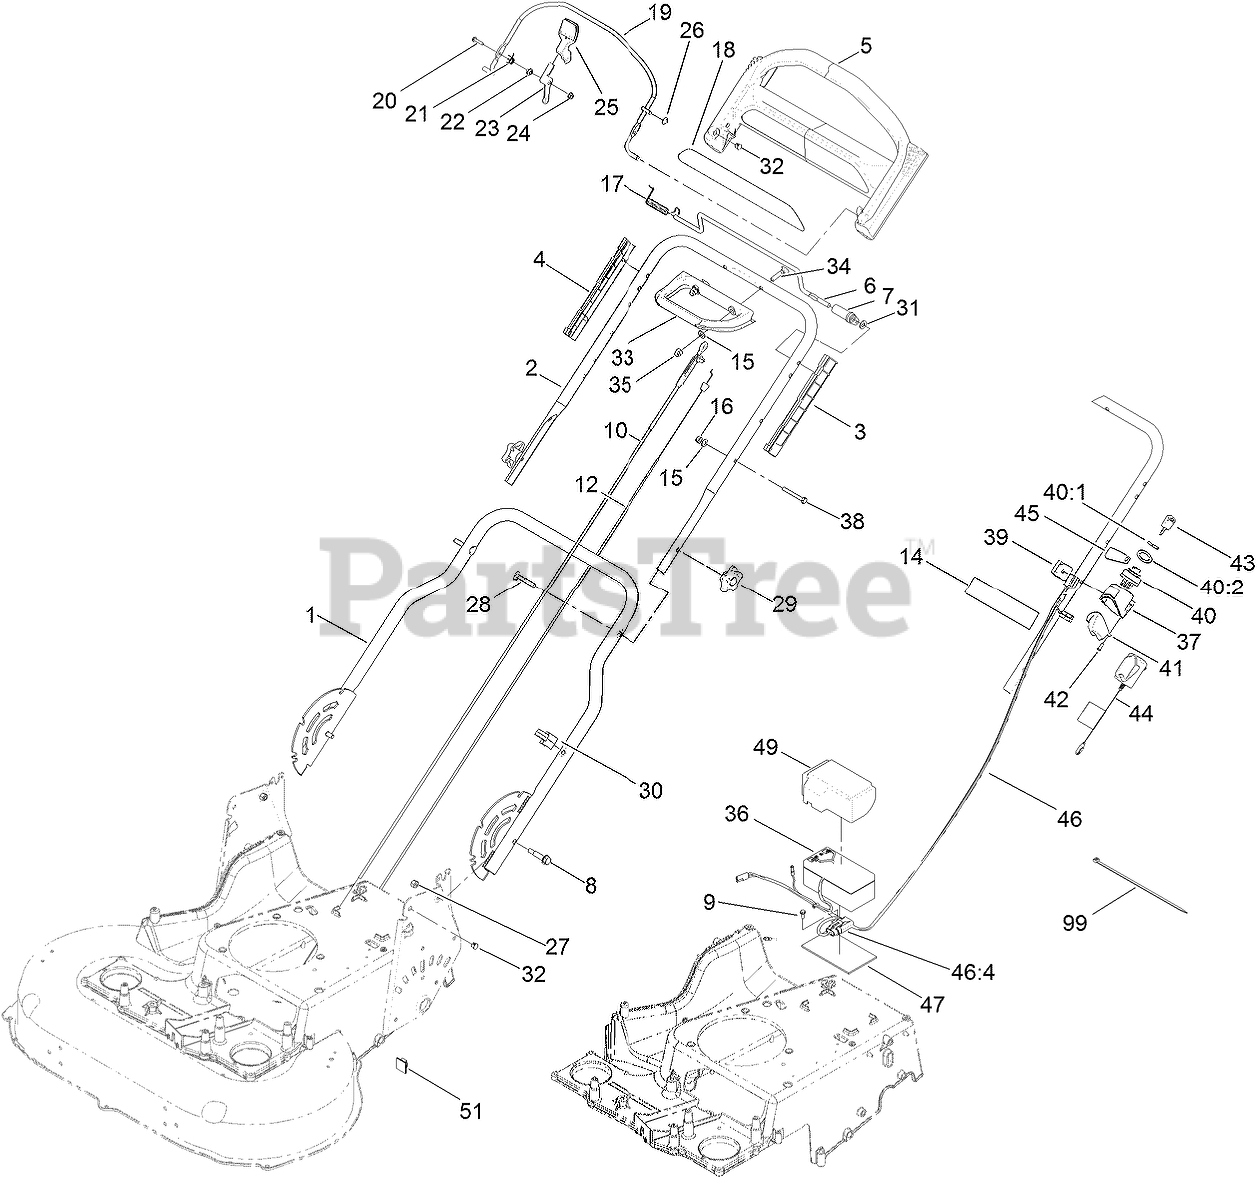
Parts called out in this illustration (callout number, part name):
1	HANDLE-LOWER
2	HANDLE-UPPER
3	GUIDE-LH
4	GUIDE-RH
5	HANDLE-CONTROL
6	BAR-CONTROL, TRACTION
7	LEVER-TRACTION
8	BOLT-SHOULDER, HHF
9	SCREW-TAPTITE
10	CABLE-BRAKE, BBC
12	CABLE-TRACTION
14	DECAL-WARNING
15	WASHER-FLAT
16	NUT-LOCK, NI
17	Spring-Torsion
18	DECAL-HANDLE
19	BAIL-BRAKE
20	SCREW-HWH
21	SPRING-TORSION
22	SPACER
23	LEVER
24	NUT-LOCK, FLANGE
26	NUT-SPEED
27	NUT-LOCK, NI
28	SCREW-HANDLE
29	KNOB-HANDLE
30	GUIDE-CABLE
31	WASHER-PLAIN
32	Plug-Dome
33	HANDLE-ASSIST, TRACTION
34	SCREW-HANDLE
35	NUT-HEX, NYLON CAP
36	BATTERY-WET
37	HOUSING-SWITCH, KEY
38	SCREW-HH
39	ANCHOR-CABLE, UPPER
40	SWITCH-STARTER
40:1	NUT-HH
40:2	WASHER-TOOTH, INTERNAL
41	COVER-SWTCH
42	SCREW-PPH
44	CHARGER-CE
45	DECAL-SWITCH, IGNITION
46	HARNESS-WIRE
46:4	FUSE-40 AMP
47	FOAM-BATTERY
49	COVER-BATTERY
51	CLIP-CONDUIT
99	TIE-CABLE
